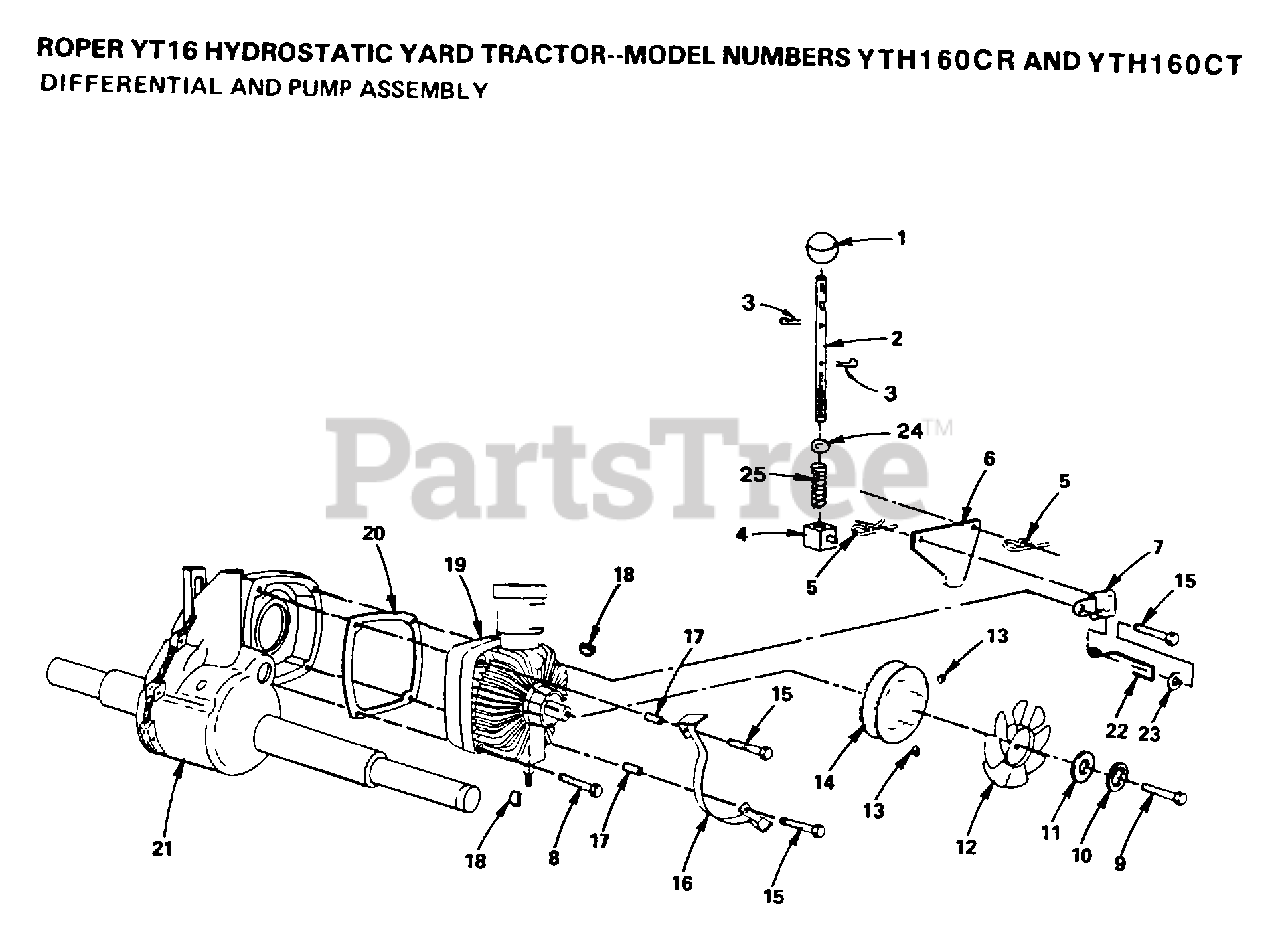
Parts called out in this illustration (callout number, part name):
1	KNOB T(3/8 HOLE)
3	COTTER PIN
4	TRUNION HYT
5	SPRING.RETAINER
6	CONTROL COAST HYT
7	BRKT ASSEM HYT
8	BOLT - HEX 3/8 - 16 X 3
9	BOLT LT
10	LOCKWASHER
11	WASHER
12	FAN HYDRO HYT
18	KEY T
19	PUMP HYDRO HYT
20	GASKET HYDRO HYT
23	WASHER
24	WASHER T
25	SPRING GTV
